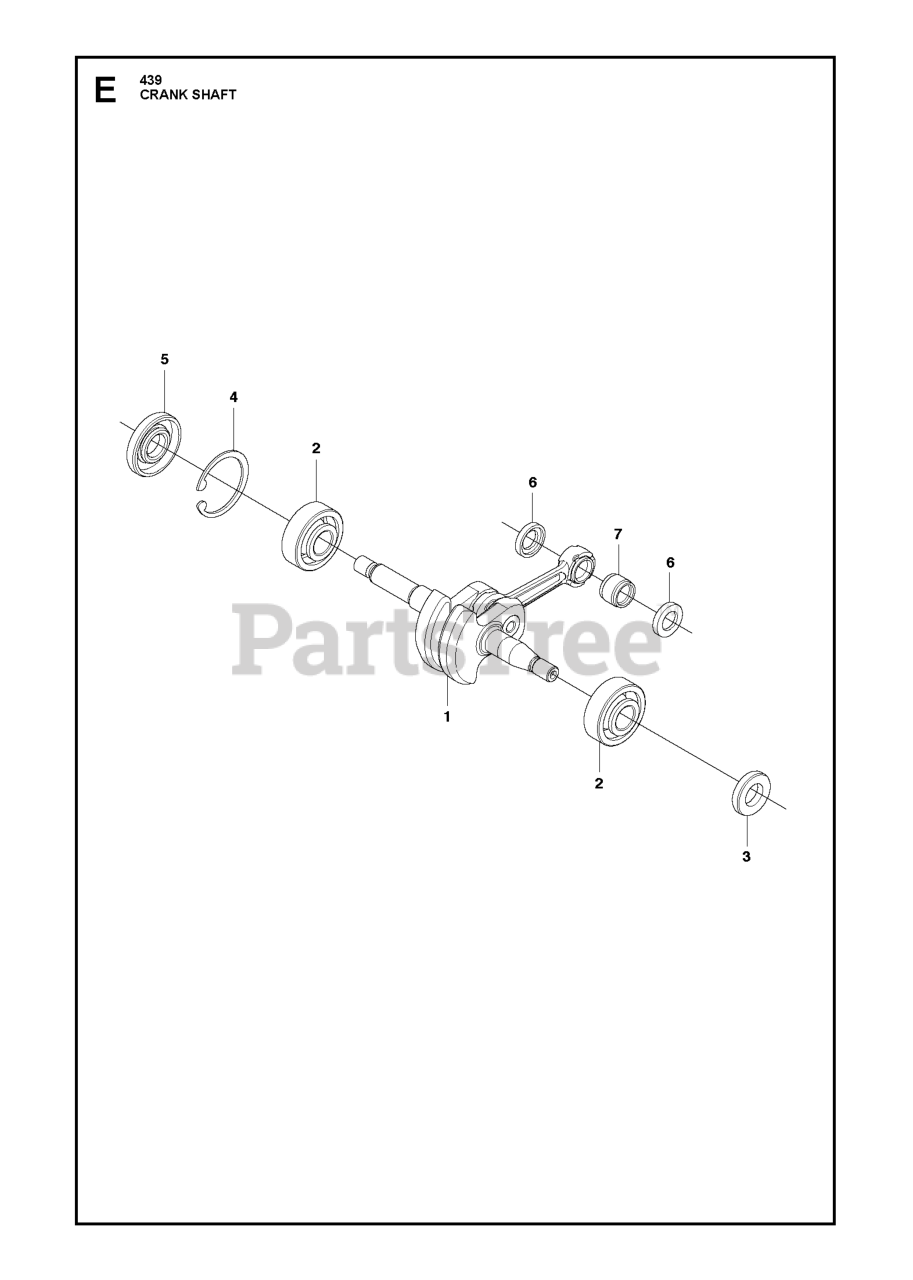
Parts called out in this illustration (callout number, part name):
1	SHAFT COMP
2	BEARING Z285021240
7	ROLLER BEARING
